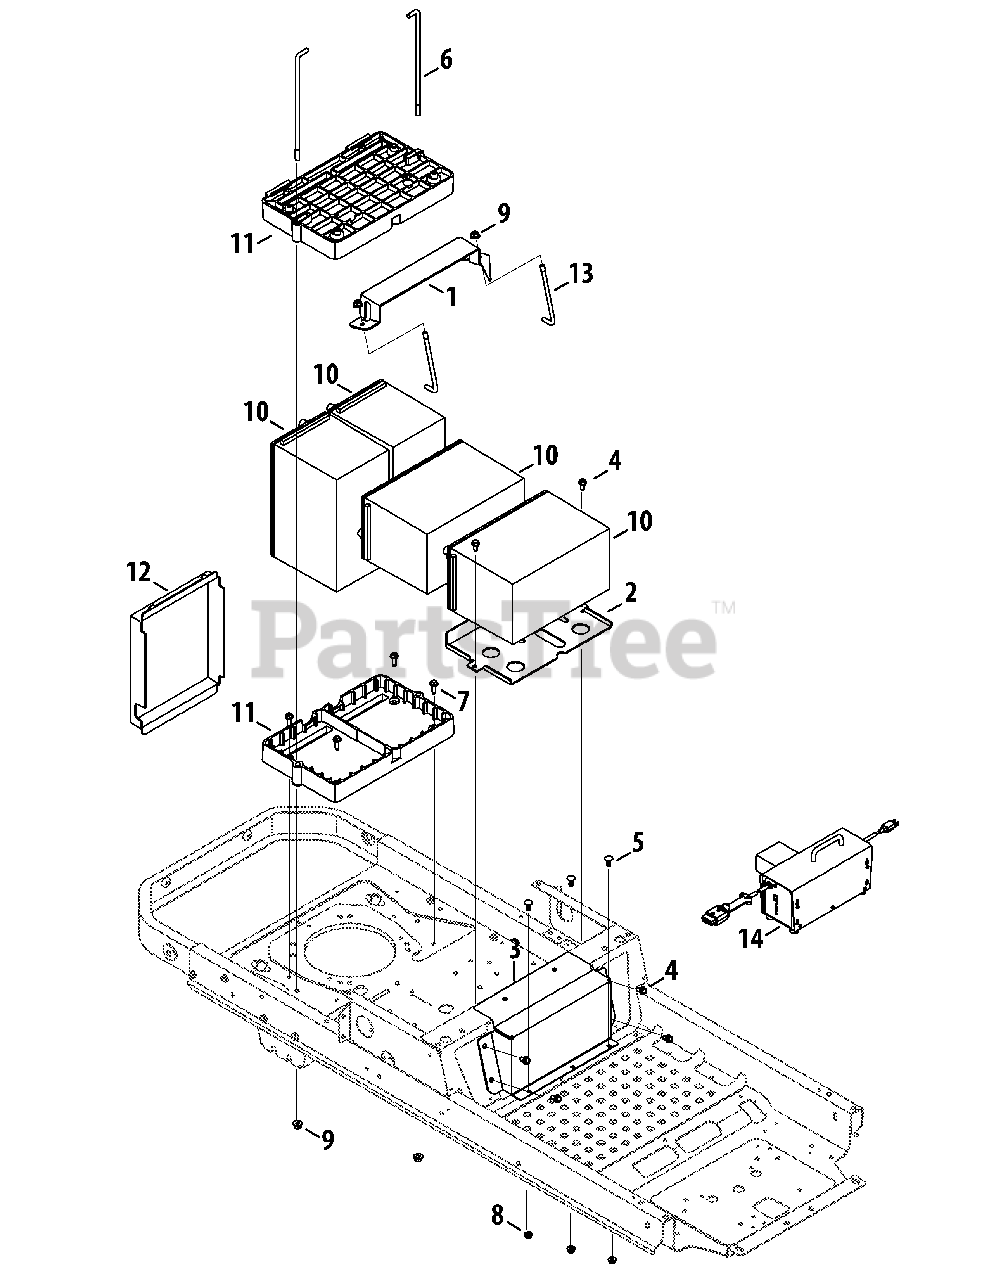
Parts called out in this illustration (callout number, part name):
1	Battery Clamp
2	Battery Tray, Front
3	Battery Clamp, Front
4	Hex Washer Screw, 5/16-18 x .750
5	Carriage Bolt, 5/16-18 x .750
6	Battery Hold Down Bolt, 3/8-16
7	Hex Washer Screw, 5/16-18 x 1.000
8	Flange Lock Nut, 5/16-18
9	Flange Lock Nut, 3/8-16
10	Battery, 12V
11	Battery Tray
12	Battery Terminal Cover
13	Battery Hold Down Bolt, 3/8-16
14	Battery Charger
